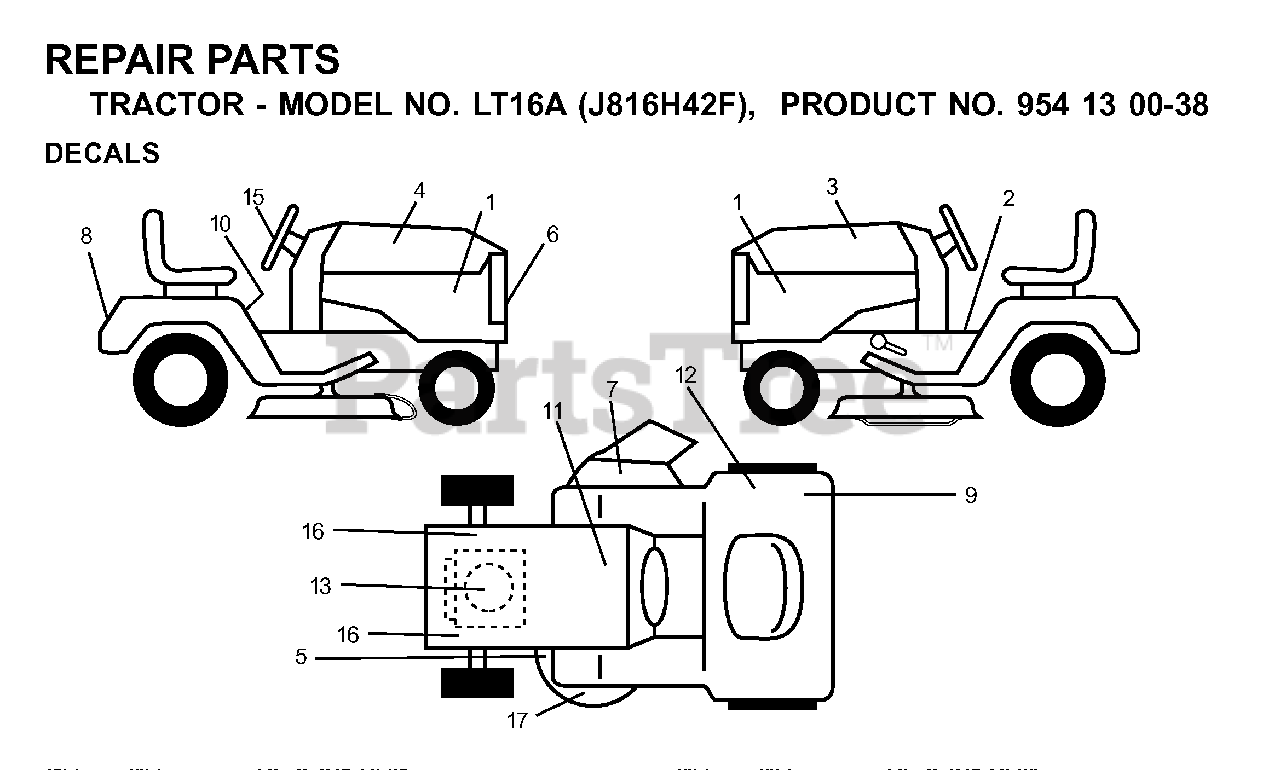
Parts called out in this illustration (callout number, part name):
2	DECAL PARK BRAKE
5	DECAL V BELT SCHEMATIC
7	DECAL MOWER CUT/FINGER
9	DECAL CERTIFICATION
10	DECAL READ OWNER'S MAN SYMS
11	DECAL BTRY SYMBOLS
12	DECAL EUROPE STANDARD CE
